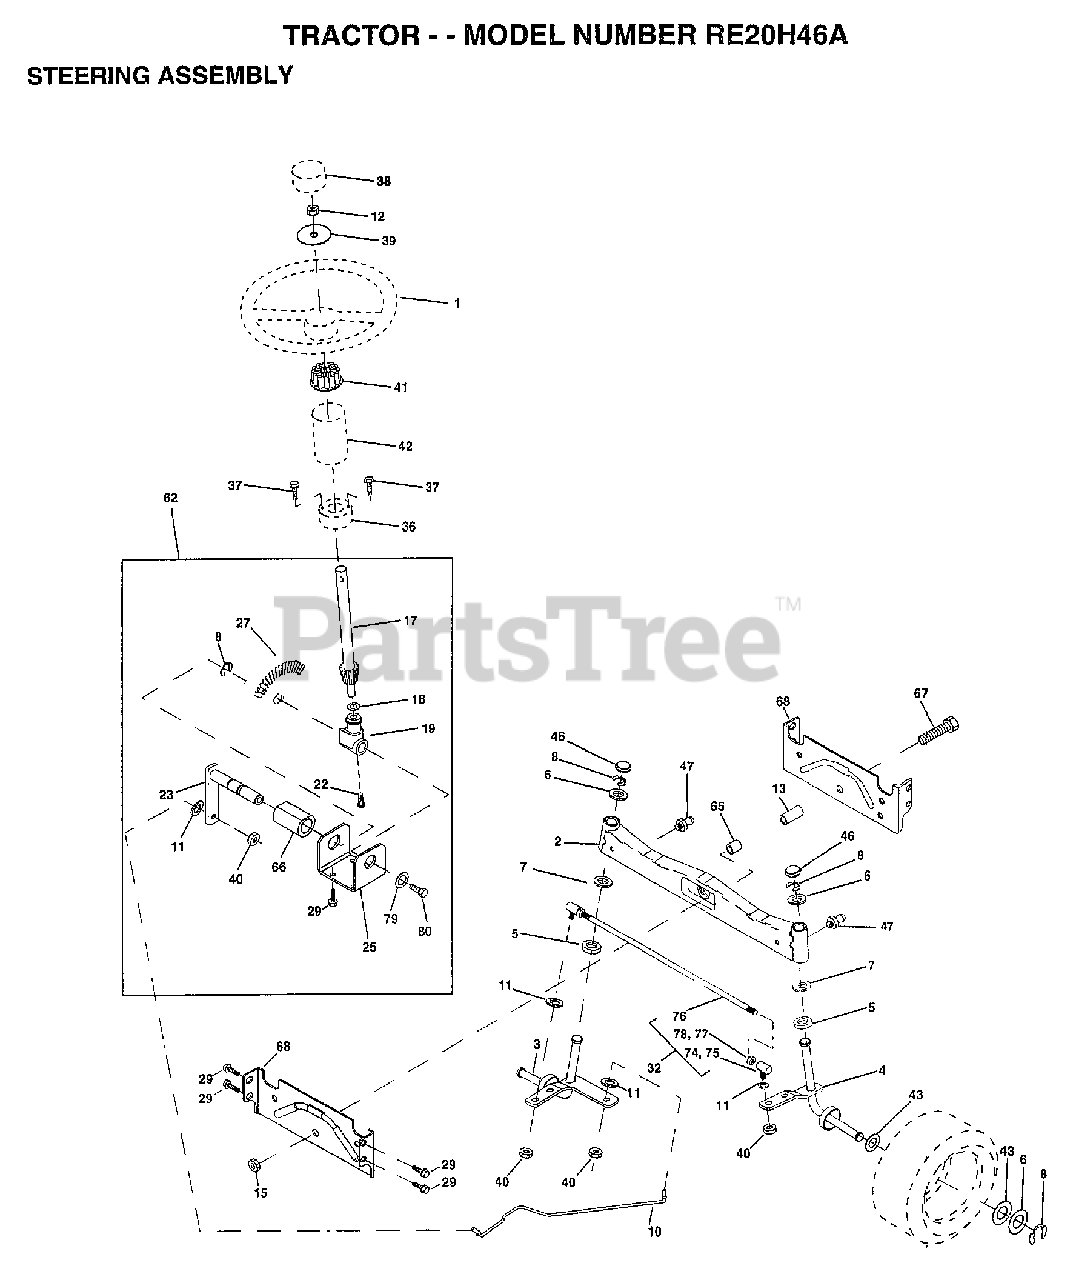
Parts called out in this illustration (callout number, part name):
3	"SPINDLE ASM,LH"
4	"SPINDLE ASM,RH"
5	WASHER .T
6	WASHER
7	WASHER
8	RING
10	LINK.DRAG
11	LOCKWASHER
13	BEARING.FRT.SPACER.AXLE
15	"NUT-LOC,FLANGE LT"
17	SHAFT ASM STEERNG
18	THRUST WASHER
19	SUPPORT.SHAFT.STEER
22	SCREW.HX.WSH.HD
23	SHAFT.ASM.PITMAN
25	BRKT-STEERING
27	GEAR SECTOR
29	SCREW
32	ROD.ASM.TIE.BALL
36	BUSHING.STRG.3/4
37	"SCREW-TT,10-32 FL"
38	"INSERT,STR WHEEL"
39	WASHER
40	GRIPCO NUT
41	ADAPTER LT
42	BOOT SHAFT STEER
43	WASHER
44	EXT SHAFT STEERIN
46	CAP
47	ZERK M
51	NUT
54	BOLT
62	KIT.STEER.ASM.LT
63	BOLT
65	SPACER AXLE
66	"BEARING-ARM,PITMA"
67	BOLT
68	BRACE AXLE
74	JOINT.RH
75	JOINT.LH
77	NUT
78	NUT
79	WASHER
80	BOLT.HX.NYLON3/8-16X3/
